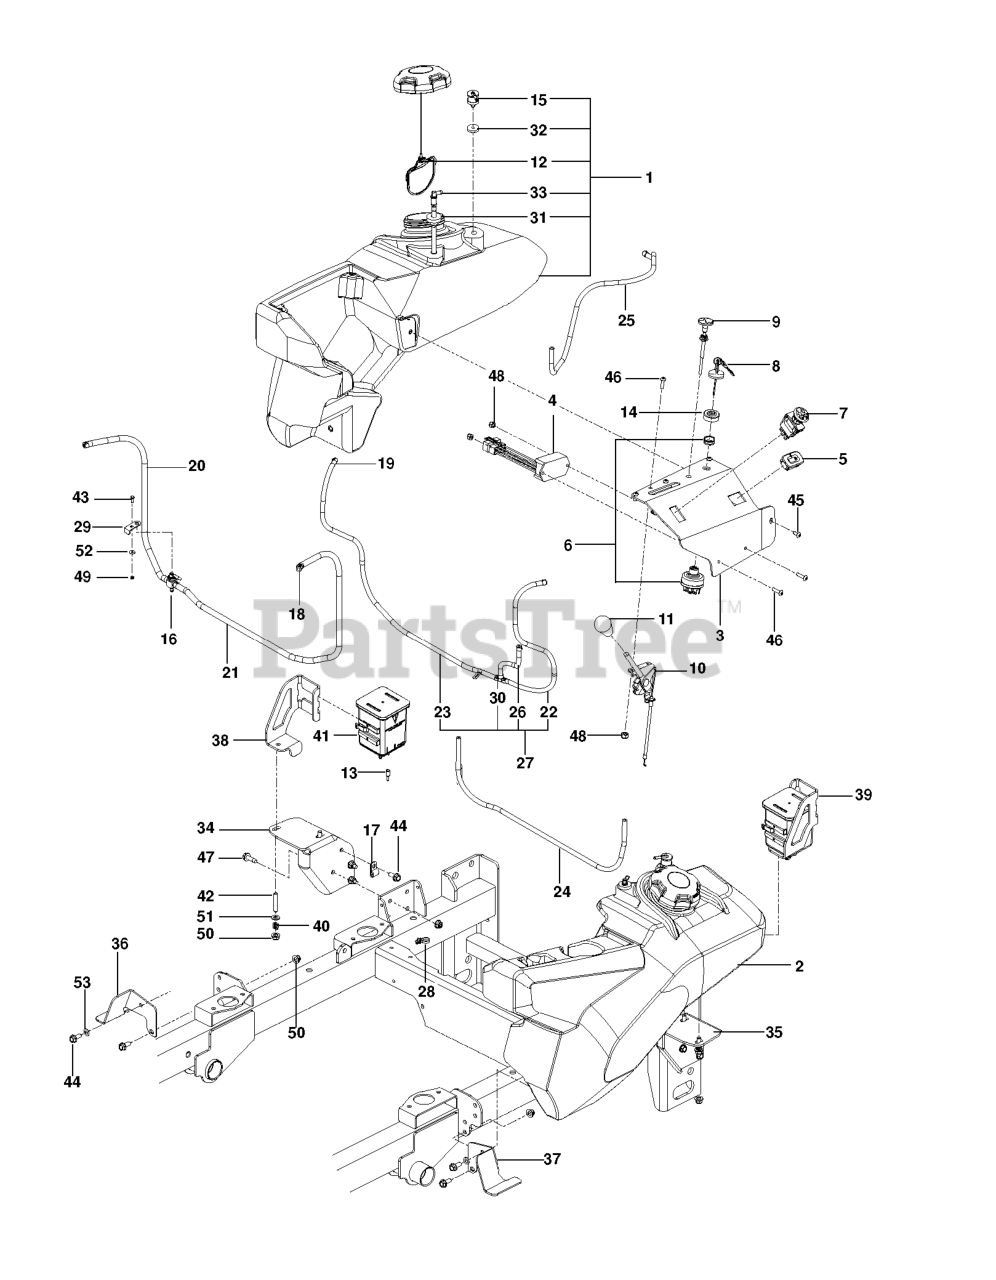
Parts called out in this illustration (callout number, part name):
1	RT FUEL TANK ASM EPA
2	LT FUEL TANK ASM EPA
3	PANEL.CONTROL.GAS.GRAY
4	TIMER, SEAT
5	HOUR METER
6	SWITCH, IGNITION, INDAK
7	RP SWITCH.PTO.TERMINAL.STD.RED
8	KEY, IGNITION
9	CABLE, CHOKE, 48"
10	CABLE, THROTTLE, 46"
11	KNOB - SHIFT
12	CAP, FUEL
13	CAP, VINYL
14	CAP IGNITION NUT
15	VALVE.FUEL.CHECK
16	FUEL VALVE
17	DOUBLE TUBE CLAMP
18	HOSE CLAMP
19	CLAMP, HOSE
20	LINE, FUEL, 22"
21	LINE, FUEL, 38"
22	HOSE, 3/16" VAPOR, 21"
23	HOSE, VAPOR 3/16 X 39"
24	HOSE, VAPOR 3/16 X 30"
25	FUEL LINE 33"
26	HOSE, 3/16" VAPOR, 7-1/2"
27	ASSEMBLY, VAPOR LINE
28	TIE WRAP, 8-3/8", W/CLIP
29	BRACKET,FUEL VALVE, BLACK
30	TEE, FUEL LINE 3/16"
31	RUBBER GROMMET
32	GROMMET, CHECK VALVE
33	FITTING, FUEL
34	MOUNT, RT TANK, BLK
35	MOUNT, LT TANK, BLK
36	XX MOUNT, TANK, RT-BLK
37	MOUNT, TANK, LT-BLK
38	MOUNT, CANISATER, RT
39	MOUNT, CANISTER, LT
41	CANNISTER, CARBON
42	STUD, 5/16C
43	HCS 1/4C X 3/4 HCS
44	HHFS 5/16-18 X 3/4
45	SCR #10-24 X 3/8 SKT HD BLK OX
46	SCR #10-24 X .75 SKT HD BLK
47	RP BLT 5/16-18 X 1 THRD FORM D
48	NUT 10-24 NYLOC
49	JAM NUT 1/4C (2 2 PW01)
50	5/16-18 NYLOC FLANGE NUT
51	FLAT WASHER 5/16 SAE
52	WASHER 1/4 FLAT
53	WASH 5/16 DISC SPRING ZD
